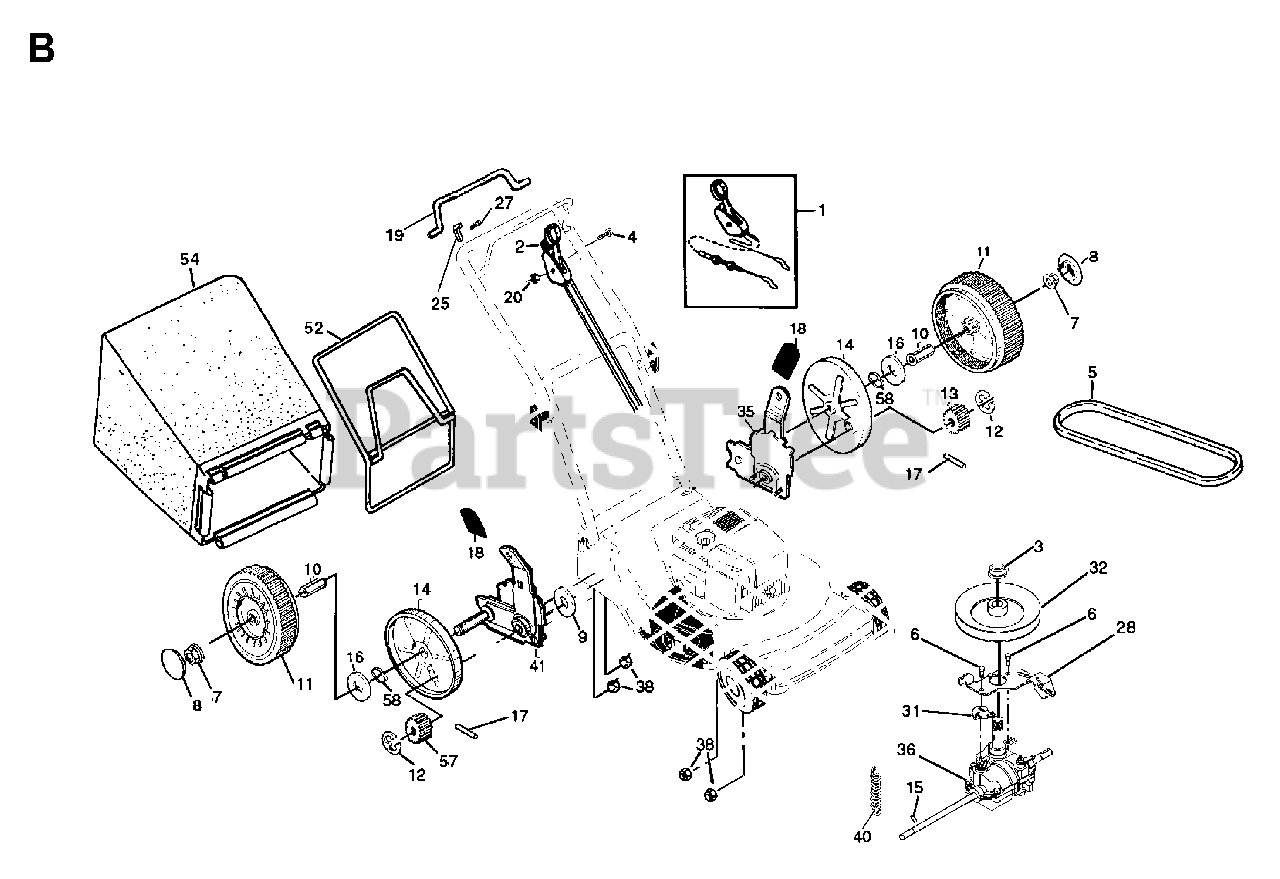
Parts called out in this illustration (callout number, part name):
1	SPEED CONTROL
2	KIT/HEAD CONTROL
3	METRIC NUT
4	SCREW 1/4-20 X 2.12
5	DRIVE BELT
7	HEX FLANGE LOCKNT
9	THRUST WASHER
10	BUSHING PM
11	WHEEL ASSY
12	E-RING 7/16 RE
14	DUST SHROUD PM
15	PIN.SPRING.THRUST
16	WASHER FLUT
17	DRIVE PAWL
18	SELECTOR KNOB
19	DRIVE CONTROL BAR
25	UPSTOP BRACKET
27	TAPPING SCREW
36	TRANSMISSION
38	NUT
58	WAVE WASHER
